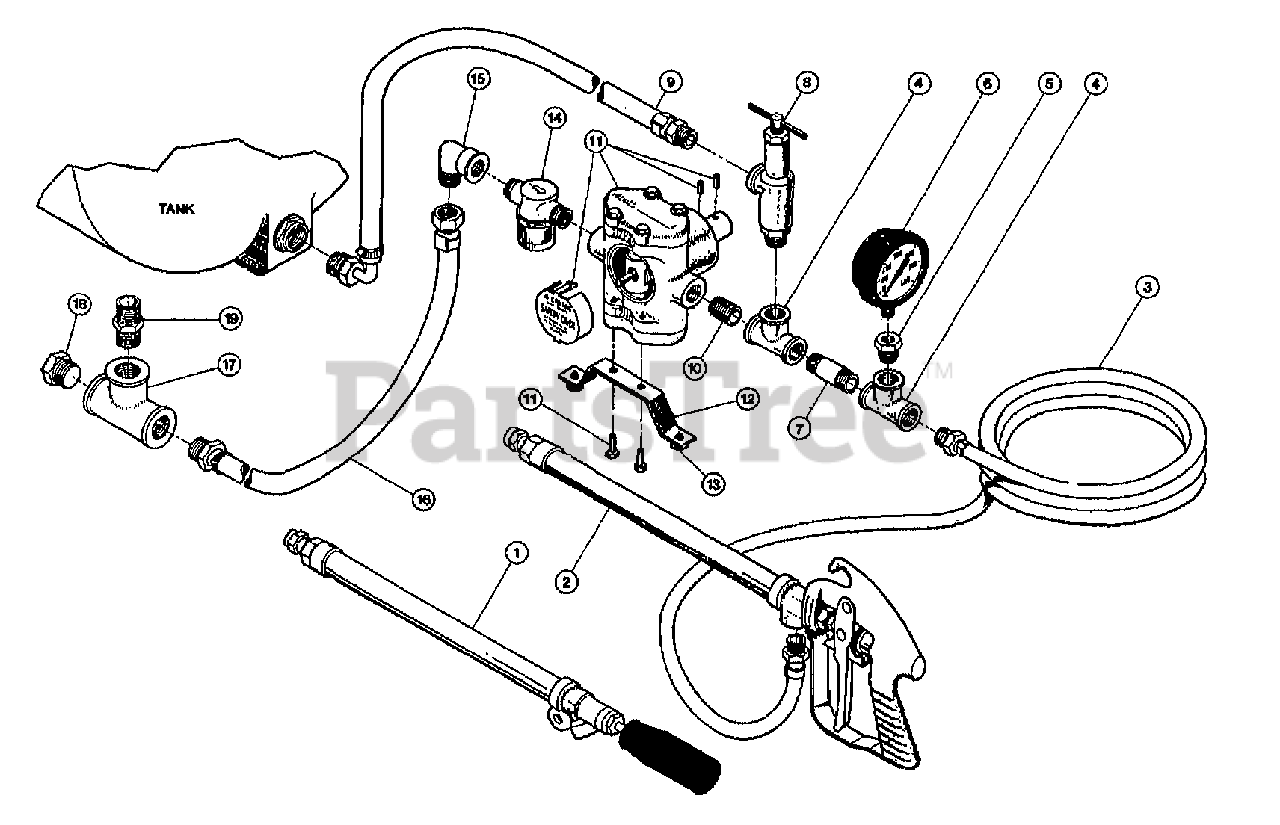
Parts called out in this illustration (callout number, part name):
1	GUN-TWIST SPRAY W143BR1/2
2	GRIP-PISTOL W43H6BR SPRAY GUN
3	HOSE-3/8 X 25' W2075660
4	TEE-1/2" PIPE W20983014
5	PIPE-BUSHING REDUCING
6	GAUGE-GLYCERINE PRESS WLFS220
7	NIPPLE-PIPE 50X2 GALVANIZED
8	VALVE PRESS.
9	HOSE-RETURN LINE W2075603
10	NIPPLE-1/2" CLOSE W20981014
11	PUMP-TWIN PISTON
12	ARM-TRQ 25G SPRAY W28200028
13	BUMPER-RUBBER TORQUE ARM
14	STRAINER W33500079
15	ELBOW-1/2" STREET WSE12
16	HOSE-17" SUCTION W2075661
17	TEE-3/4 PIPE NYL WTT34
18	PLUG-3/4" PLASTIC WF3400
19	NIPPLE-3/4 CLOSE WM1400
